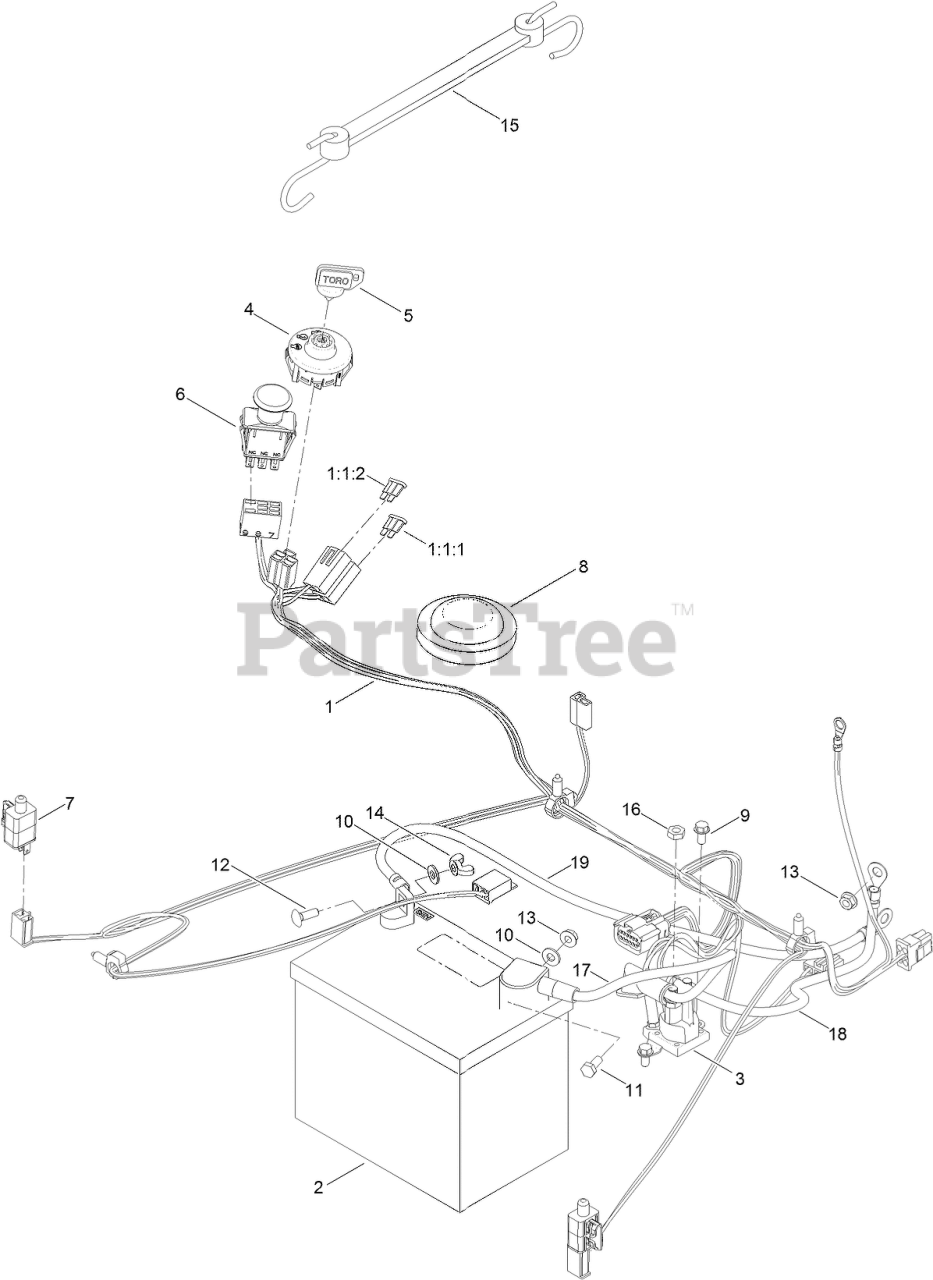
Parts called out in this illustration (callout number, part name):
1	HARNESS-WIRE
1:1:1	FUSE-BLADE, 30 AMP
1:1:2	FUSE-BLADE, 25 AMP
2	BATTERY
3	SOLENOID
4	SWITCH-IGNITION
5	KEY-IGNITION
6	SWITCH-PTO
7	SWITCH
8	SWITCH-SEAT
9	SCREW-HWH
10	WASHER-FLAT
11	SCREW-HH
12	BOLT-CARR
13	NUT-HF
14	NUT-WING
15	HOLDDOWN-BATTERY
16	NUT-JAM
17	CABLE-BATTERY, RED
18	CABLE-BATTERY, POSITIVE
19	CABLE-BATTERY, BLACK
